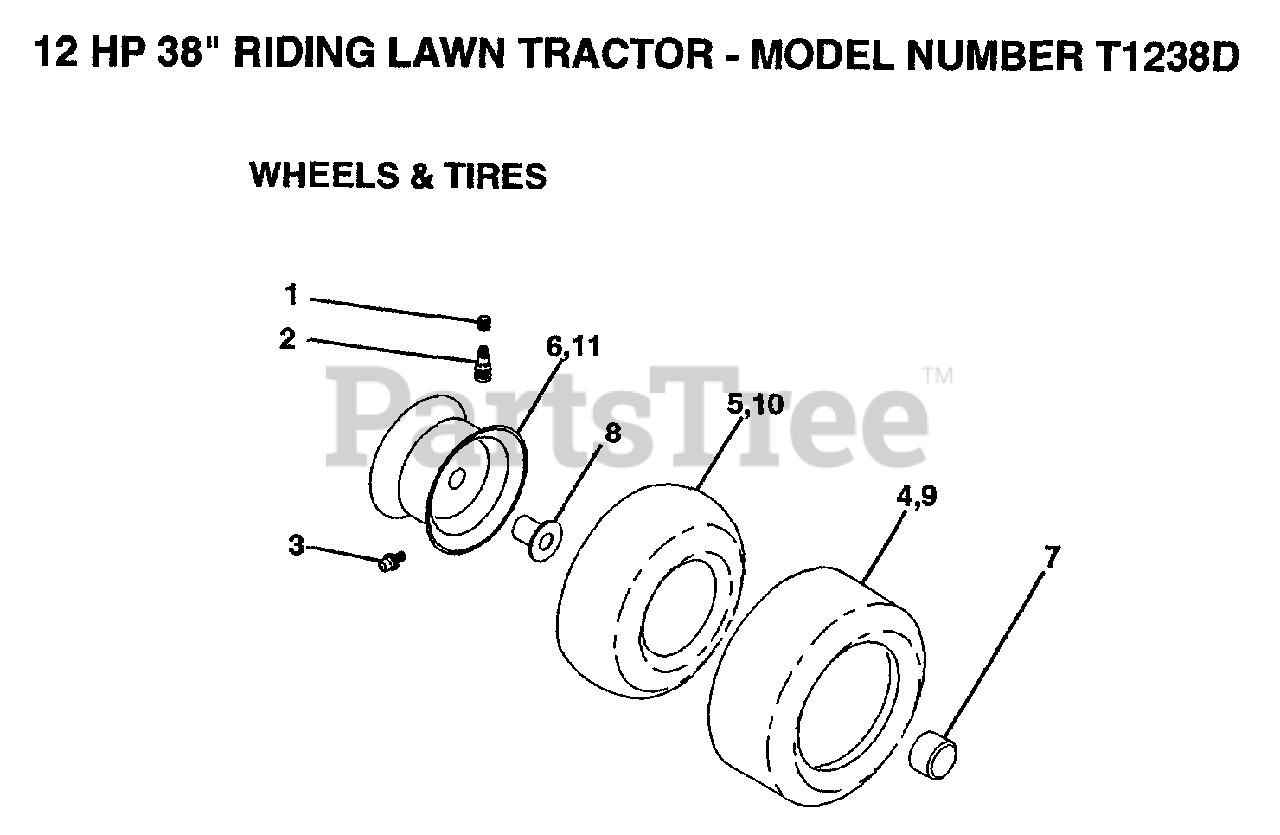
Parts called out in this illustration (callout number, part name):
1	VALVE CAP
2	VALVE STEM LT
3	FITTING LT
5	TUBE.5.3/4.5/6
7	HUB CAP
8	"FLANGE, BEARING"
10	TUBE.18X9.5-8
